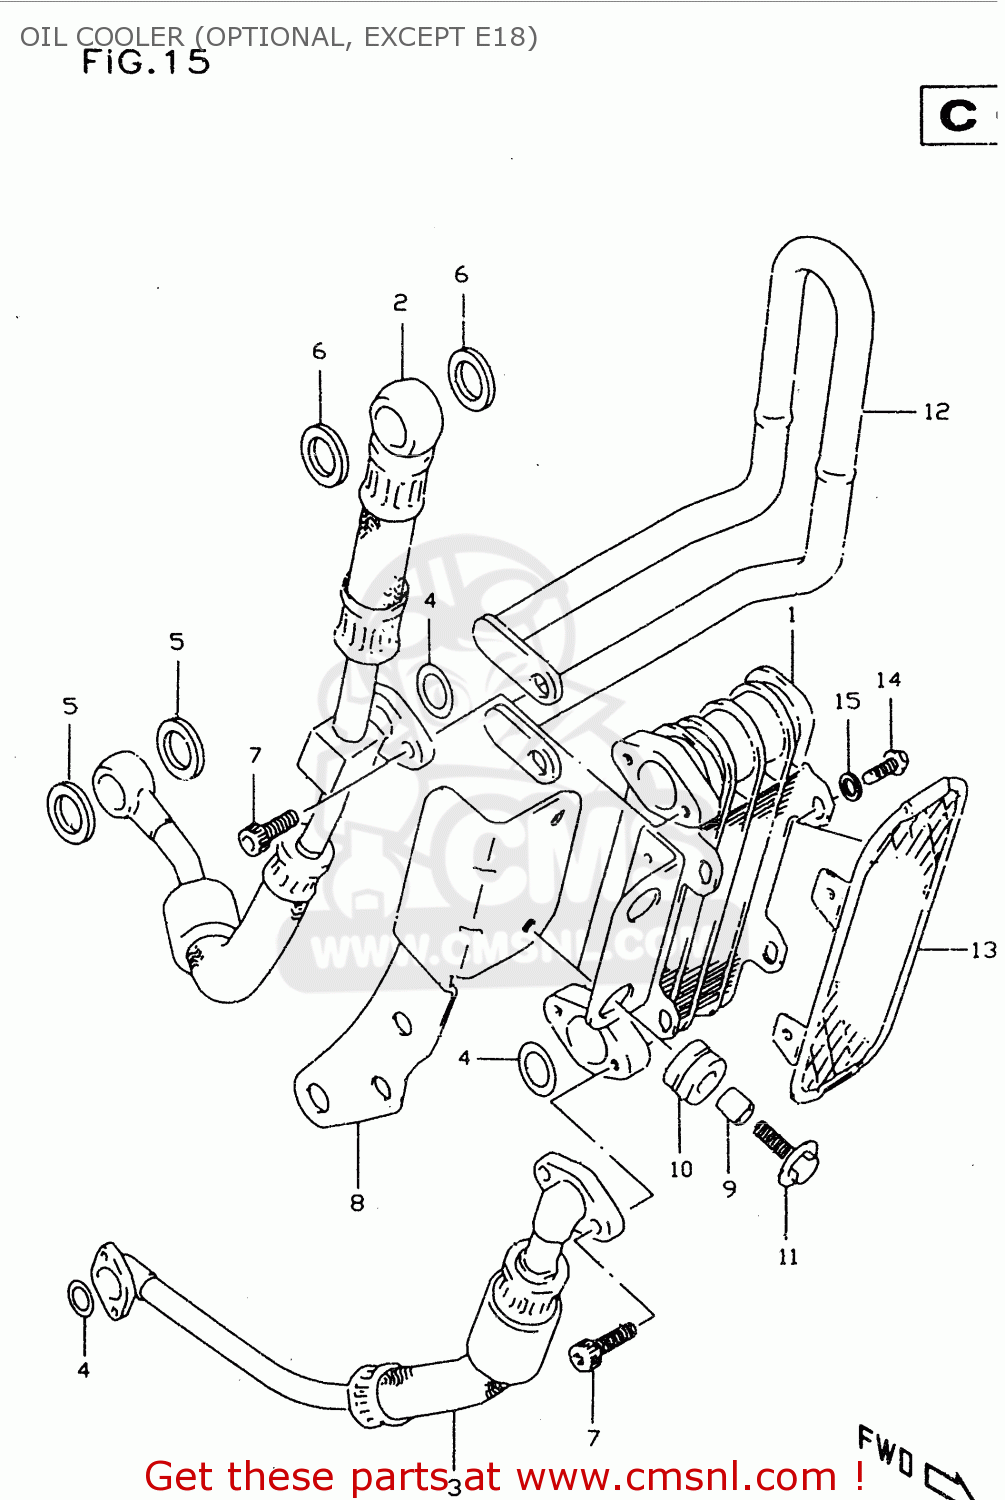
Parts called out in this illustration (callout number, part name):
1	COOLER ASSY,OIL
2	HOSE,OIL COOLER UPR
3	HOSE,OIL COOLER LWR
4	O RING(D:2.4,ID:12.3)
5	GASKET(12X17X1) (NAS)
6	GASKET(16X22X2) (NAS)
7	BOLT,OIL FILLE
8	BRACKET,OIL COOLER
9	SPACER(6.5X10X10)
10	CUSHION
11	BOLT 6X20
12	GUARD,OIL COOLER
13	BUMPER,OIL COOLER
14	BOLT
15	LOCK,WASHER
